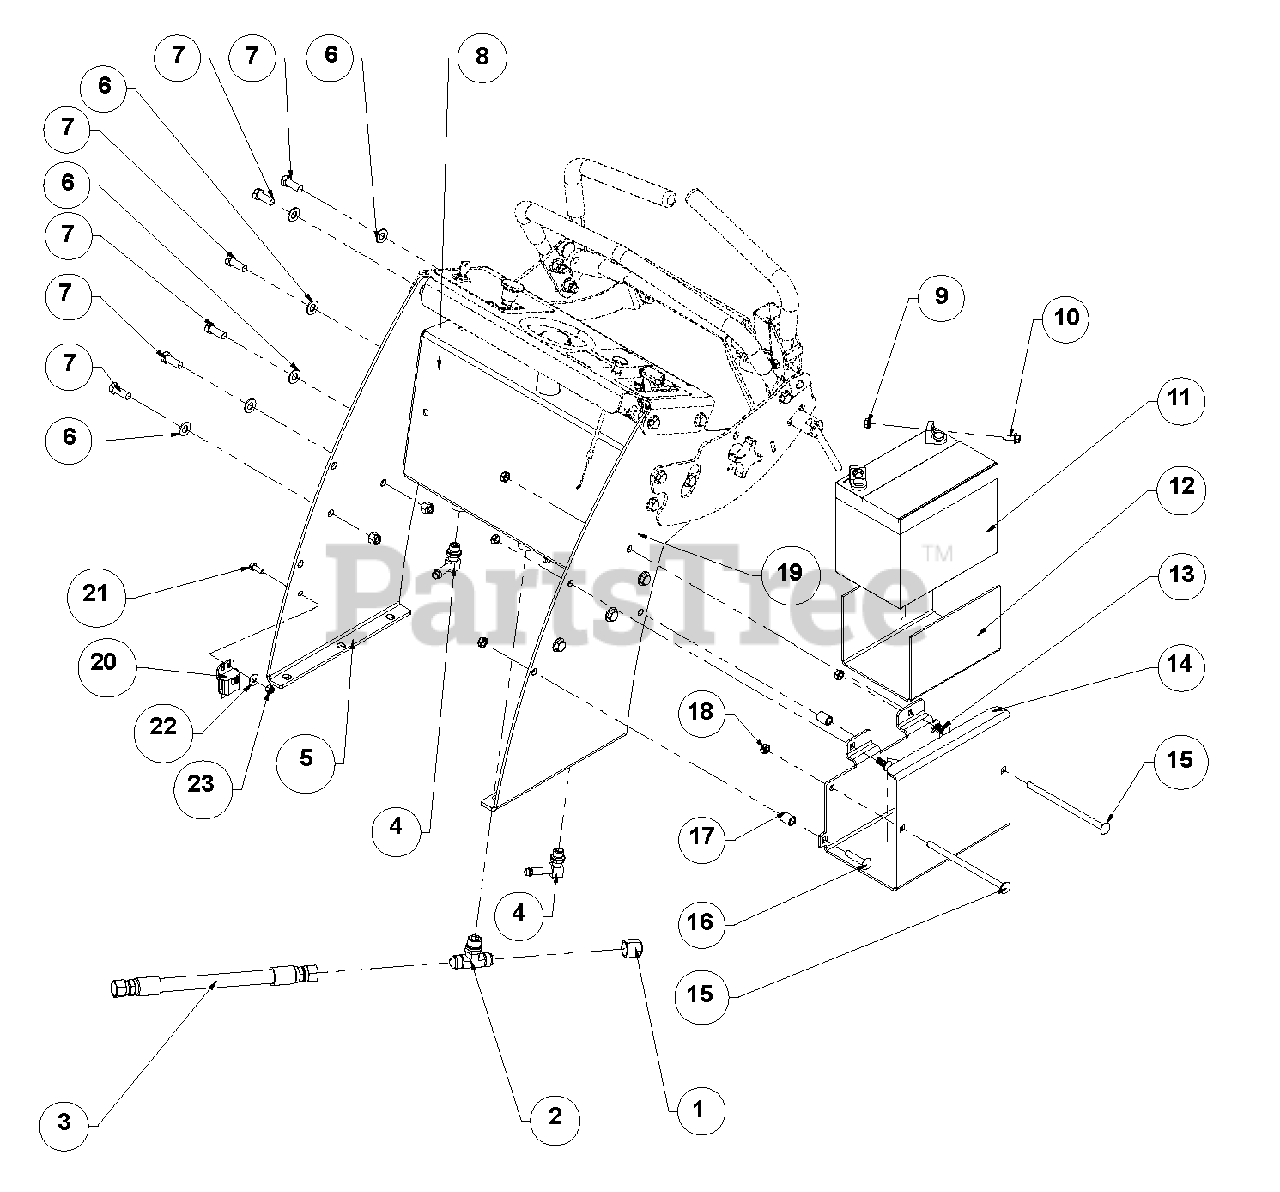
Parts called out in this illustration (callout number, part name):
1	Cap, .75-16 JIC
2	Fitting, TMB JIC
3	Hose, Hydraulic-8-12FJIC 12
4	Fitting, 90 .5625 MOR x .3750 Hose
5	Weldment, Right Hand Handle Tower
6	Washer, .406 x .813 x .065 Flat
7	Bolt, .38-16 x 1.00 Hex 5
8	Weldment, Tank
9	Locknut, .25-20 WHIZ
10	Bolt, .25-20 x .625 WSH
11	Battery, 12V
12	Strip, Rubber
13	Bolt, .3125-18 x .750 Round Head Square Neck
14	Tray, Battery 1948 Hydro
15	Bolt, .3125 x 6 Long Neck Round Head D-Z
16	Bolt, .3125-18 x 1.50 Round Head Square Neck
17	Bushing, .364 x .540 x .700
18	Locknut, .3125-18 Nyloc
19	Weldment, Left Hand Handle Tower
20	Module, Electronic (400)
21	Bolt, .25-20 x .750 Hex 5 (400)
22	Washer, .250 Regular Flat (400)
23	Locknut, .25-20 Nyloc (400)
24	Harness, Electric Start Walk (402,403)
25	Harness, Wire Non Elbow Steel Walk (400)
